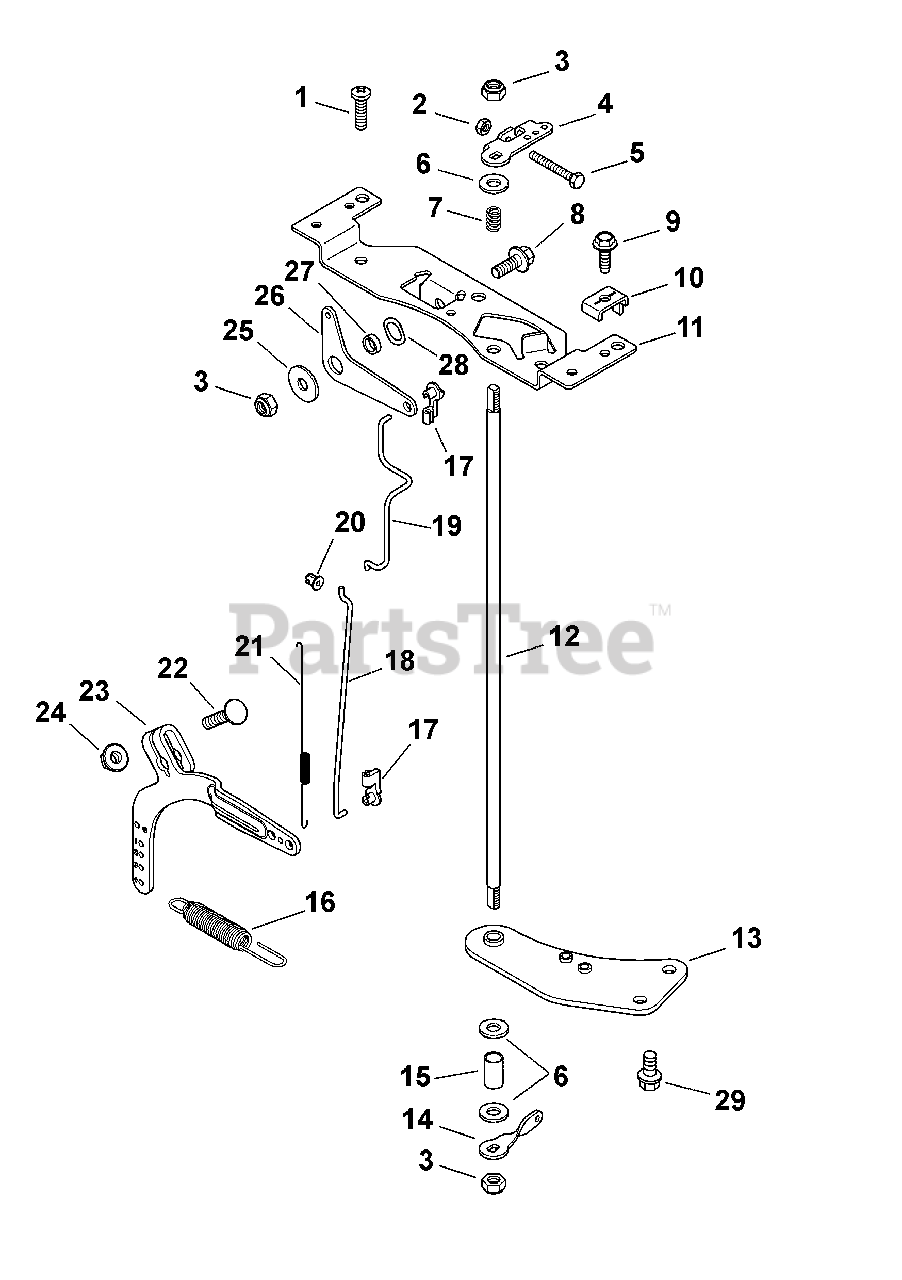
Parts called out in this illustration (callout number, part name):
1	Screw, Phl Hd 11-16X3/4"
3	Nut, Lock M6X1.0
4	Lever, Throttle Control
5	Screw, Cap M4X0.7X30
6	Washer, Flat 1/4"
7	Spring, Throttle Shaft
8	Screw, FLG M6X1.0X16
9	Screw, Flg Thd Frm M5X0.8X16
10	Clamp, Cable
11	Bracket, Control
12	Shaft, Throttle
13	Bracket, Throttle Shaft
14	Lever Throttle Control
16	Spring, Governor
17	Bushing, Throttle Linkage
18	Linkage, Throttle
19	Linkage, Choke
20	Bushing, Linkage Retaining
21	SPring, Linkage
22	Bolt, Rd Hd Sq Neck M6X1.0X25
23	Lever, Governor
24	Nut, Flg M6x1.0
25	Washer, Flat 1/4"
26	Lever, Choke
28	Washer, Spring 3/8"
29	Screw, Flg Thd Frm M6x1.0x16
